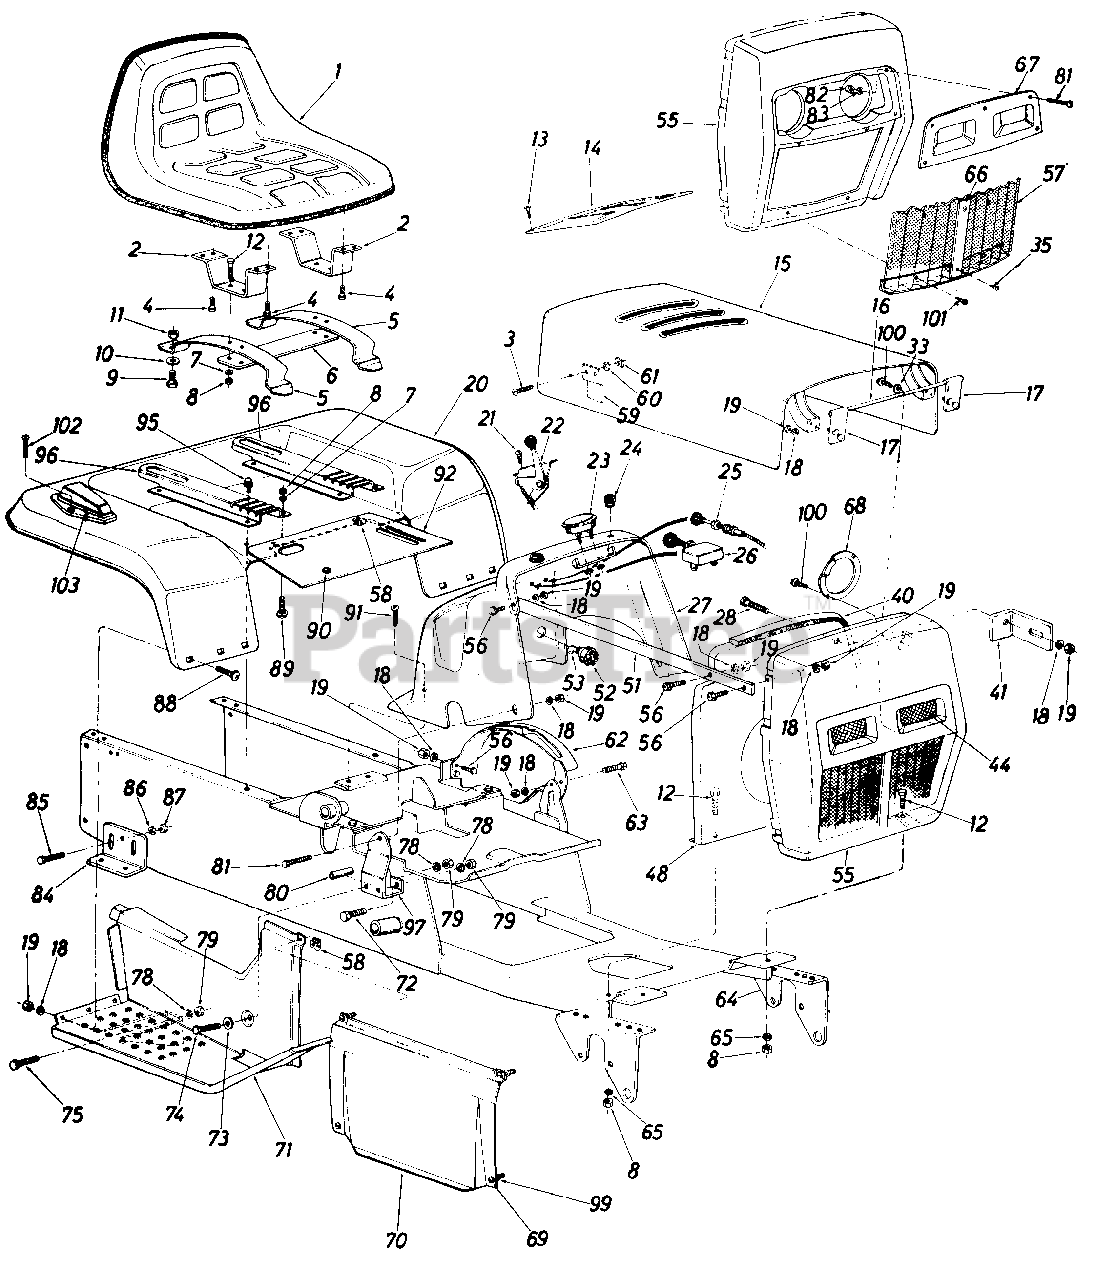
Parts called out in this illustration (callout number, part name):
1	Seat Ass'y. Comp.
2	Seat Support Brkt.
3	Truss Hd. Mach. Scr. #10-24 x.38" Lg.
4	Hex Wash. Hd. Self-Tap Scr. 3/8-16 x .75" Lg.
7	L-Wash. 5/16" Scr.
8	Hex Nut 5/16-18 Thd.
9	Nylon Scr 1/2-13 x .75" Lg.
10	Fl-Wash .531 I.D. x .930 O.D.
11	Hex Cent. L-Nut 1/2-13 Thd.
12	Hex Scr. 5/16-18 x .75" Lg.
13	Self-Tap Oval Hd. Scr. 1/2" Lg.
14	Dash Panel Cover
15	Hood Ass'y.
16	Hinge Rod
17	Hood Hinge Ass'y.
18	L-Wash. 1/4" Scr.
19	Hex Nut 1/4-20 Thd.
20	Rear Fender
21	Fl-Hd. Truss Scr. #10 x .62" Lg.
22	Throttle Control
23	Ammeter
24	Rubber Bumper
25	Choke Control
26	Light Switch
27	Dash Panel
28	Hex Scr. 1/4-20 x .62" Lg.
33	Fl-Wash. .250 I.D. x 1.25 O.D.
35	UNKNOWNW
40	Foam Strip
41	Heat Shield Brkt.
44	Head Lamp
48	Heat Shield
51	Grille Strap
52	Ignition Switch
53	Ignition Key
55	Grille
56	Hex Scr. 1/4-20 x .75" Lg.
57	Grille Screen
58	Clip-On Receptacle
59	Hood Spring
60	L-Wash. #10
61	Hex Nut #10-24
62	Speed Control Guide
63	Truss Mach. Scr. 1/4-20 x .75" Lg.
64	Frame Ass'y.
65	Bell-Wash. 5/16" Scr.
66	Moulding
67	Headlight Bezel
68	Headlight Retainer
69	1/4-Turn Stud
70	Hood Lower Side Panel
71	Foot Step Panel Ass'y.-R.H.
72	Hex Scr. 3/8-16 x 1.00" Lg. Grade 5
73	Fl-Wash. .385 I.D. x .62 O.D.
74	Hex Scr. 3/8-16 x 3.00" Lg.
75	Hex Scr. 3/8-16 x 1.00" Lg. Grade 5
78	L-Wash. 3/8" Scr.
79	Hex Nut 3/8-16 Thd.
80	Spacer .375 I.D. x .62 O.D. x 2.00" Lg.
81	Truss Mach. Scr. #10-24 x 1.0" Lg.
82	Sq. Nut #10-24 Thd.
83	Ext. L-Wash. #10 I.D.
84	Transaxle Support Brkt.
85	Rd. Hd. Rib Neck Scr. 3/8-24
86	L-Wash. 3/8" Scr.
87	Hex Nut 3/8-24 Thd.
88	Carr. Bolt 1/4-20 x .50" Lg.
89	Carr.- Bolt 5/16-18 x .62" Lg.
90	Snap Bushing
91	Fl-Hd. Self-Tap Scr. 1/4-20 x .62" Lg.
96	Seat Adjustment Brkt.
100	Thread Rolling Scr. 1/4"
101	Drive Scr. #7
102	Fl. C-Sunk AB-Tap Scr. #10x 1.0" Lg.
103	Taillight
